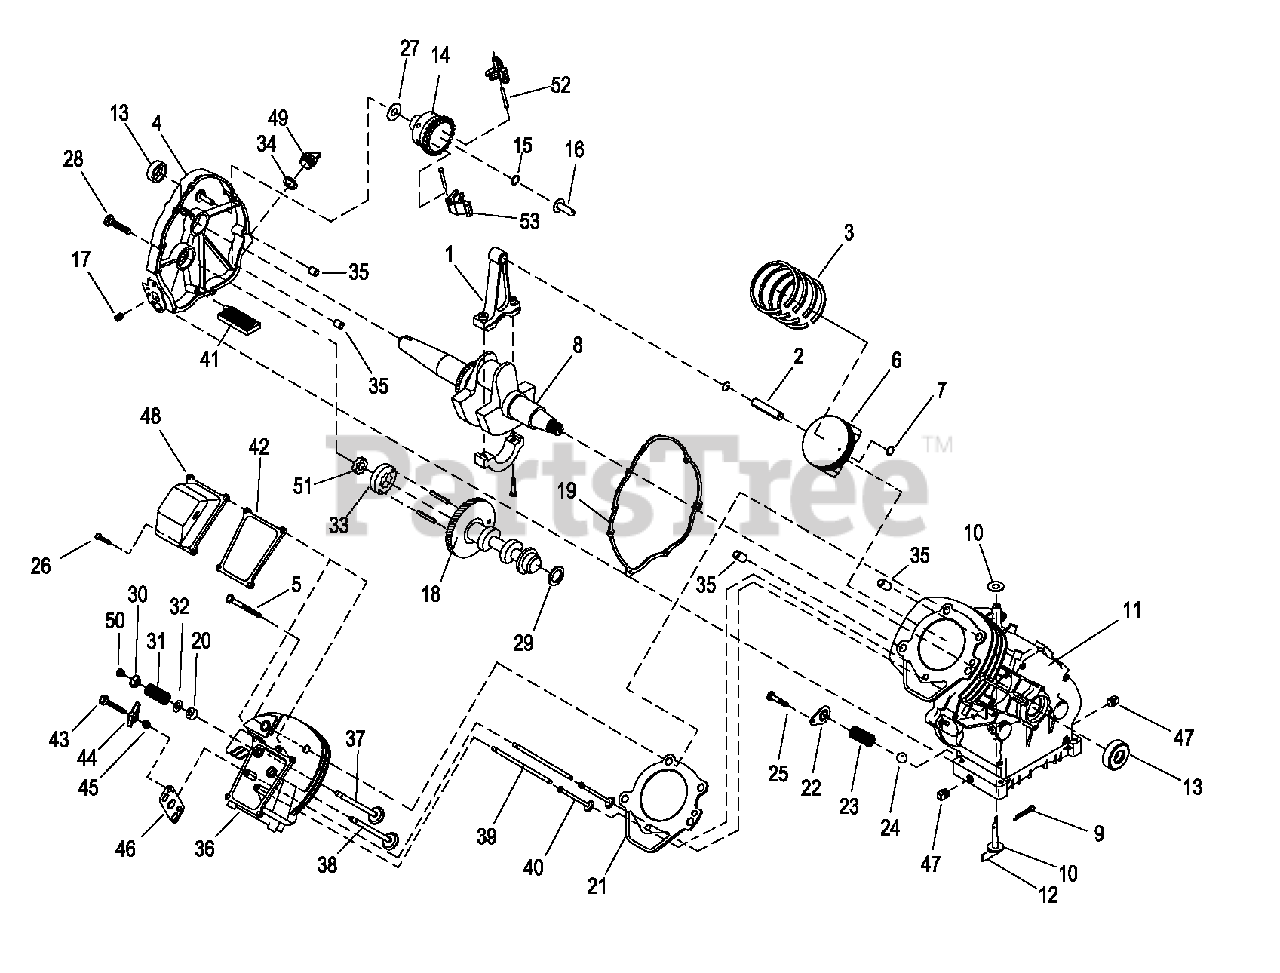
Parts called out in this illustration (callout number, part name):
1	ASSY, CONNECTING ROD
2	PIN, PISTON
3	RING SET, 75 DIAMETER
4	ASSY, GEAR COVER
5	SCREW, HHC M8-1.25 X 56
6	PISTON, COATED 75 DIAMETER
7	RETAINER, PISTON PIN
8	ASSEMBLY, CRANKSHAFT
9	PIN COTTER "R" 0.59X1/4X1-1/8
10	WASHER, FLAT 1/4", 0.15 THICK
11	CRANKCASE GH220 HS
12	ARM, GOVERNOR
13	SEAL, 28mm DIA x 41.47 VITON
14	ASSY, GOVERNOR GEAR
15	C-RING, GOVERNOR GEAR RETAINING
16	SPOOL, GOVERNOR MACHINED
17	PLUG, 1/8" NPTF PIPE
18	ASSY, CAMSHAFT 220 W/ COMP. RELEASE
19	GASKET, CRANKCASE
20	SEAL, VALVE STEM
21	GASKET, CYLINDER HEAD GH220
22	COVER, OIL PRESSURE RELIEF
23	SPRING, OIL PRESSURE RELIEF GH220
24	BALL, 11/32" DIAMETER PRESSURE RELIEF
25	SCREW, HHTT M5-0.8 X 10
26	SCREW, M6-1.0 x 12 W/LOCK WASHER
27	WASHER, THRUST GOVERNOR GEAR
28	SCREW, HHFC M8-1.25 x 35
29	WASHER, SPRING
30	RETAINER, VALVE
31	SPRING, VALVE
32	WASHER, VALVE SPRING WEAR
33	GEROTOR, OUTER
34	O-RING, 11/16-7-8" 75 DUROMETER VITON
35	SLEEVE, DOWEL PIN 12mm DIAMETER
36	ASSEMBLY, HEAD GUIDES & SEATS 220
37	VALVE, EXHAUST
38	VALVE, INTAKE
39	PUSHROD, 145.76 LENGTH GH220
40	TAPPET, 7.5mm DIAMETER
41	ASSEMBLY, OIL PICK UP GH220
42	GASKET, VALVE COVER
43	STUD, ROCKER ARM PIVOT
44	ARM, ROCKER GH220
45	NUT, JAM M-6 - 0.75 FINE THD
46	PLATE, PUSHROD GUIDE
47	PLUG, 1/4" NPTF PIPE
48	ASSEMBLY, VALVE COVER STEEL
49	PLUG, OIL FILL PLSTC,ORANGE
50	KEEPER, VALVE SPRING
51	GEROTOR, INNER
52	PIN, GOVERNOR FLYWEIGHT RETAINER
53	FLYWEIGHT, GOVERNOR
